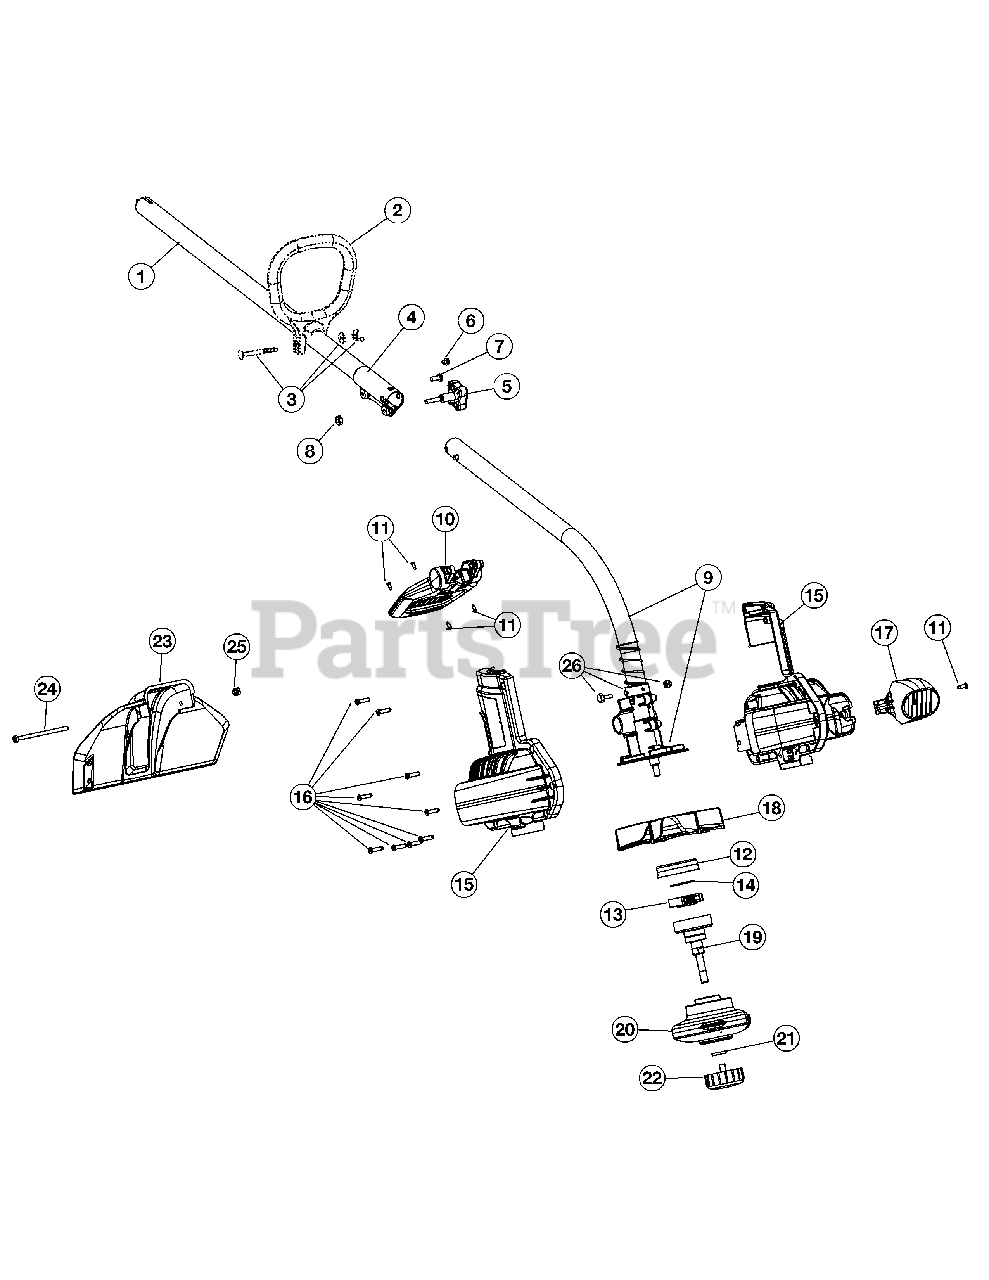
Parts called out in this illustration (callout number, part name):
1	Upper Drive Shaft Housing Assembly
2	D-Handle (includes 3)
3	D-Handle Hardware Assembly
4	Split Boom Coupler (includes 5-8)
5	Adjustment Knob (includes 8)
8	Nut
9	Lower Drive Shaft Housing Assembly (includes 26)
10	Handle Shift Assembly (includes 11)
11	Screw
12	Clutch Drum Container
13	Clutch Assembly
14	Washer
15	Housing Assembly (includes 16)
16	Screw
17	Nozzle
18	Impeller
19	Clutch Drum Assembly w/Spool Shaft
20	Fixed Line Head
21	Lock Washer
22	Bump Head Knob Assembly
23	Guard Assembly w/Blade (includes 24 & 25)
24	Screw
25	Nut
